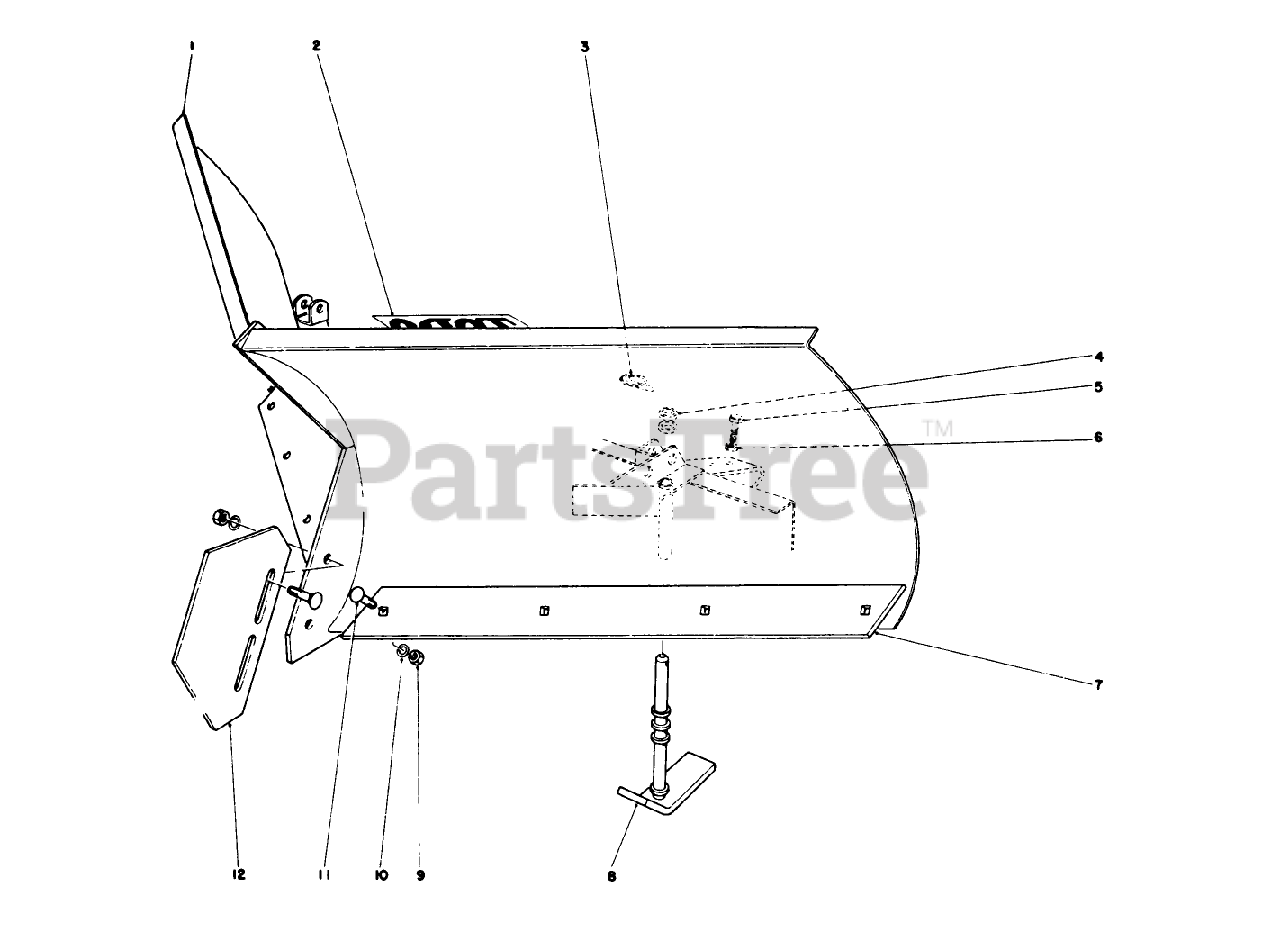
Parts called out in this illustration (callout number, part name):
1	V-Plow
2	Decal
3	PIN-LYNCH
4	SPACER TUBE B
5	SCREW-HH
6	NUT-JAM
7	Blade-Scraper
8	Skid
9	NUT-HH
10	WASHER-LOCK
11	SCREW-CARR
12	Nose Skid
